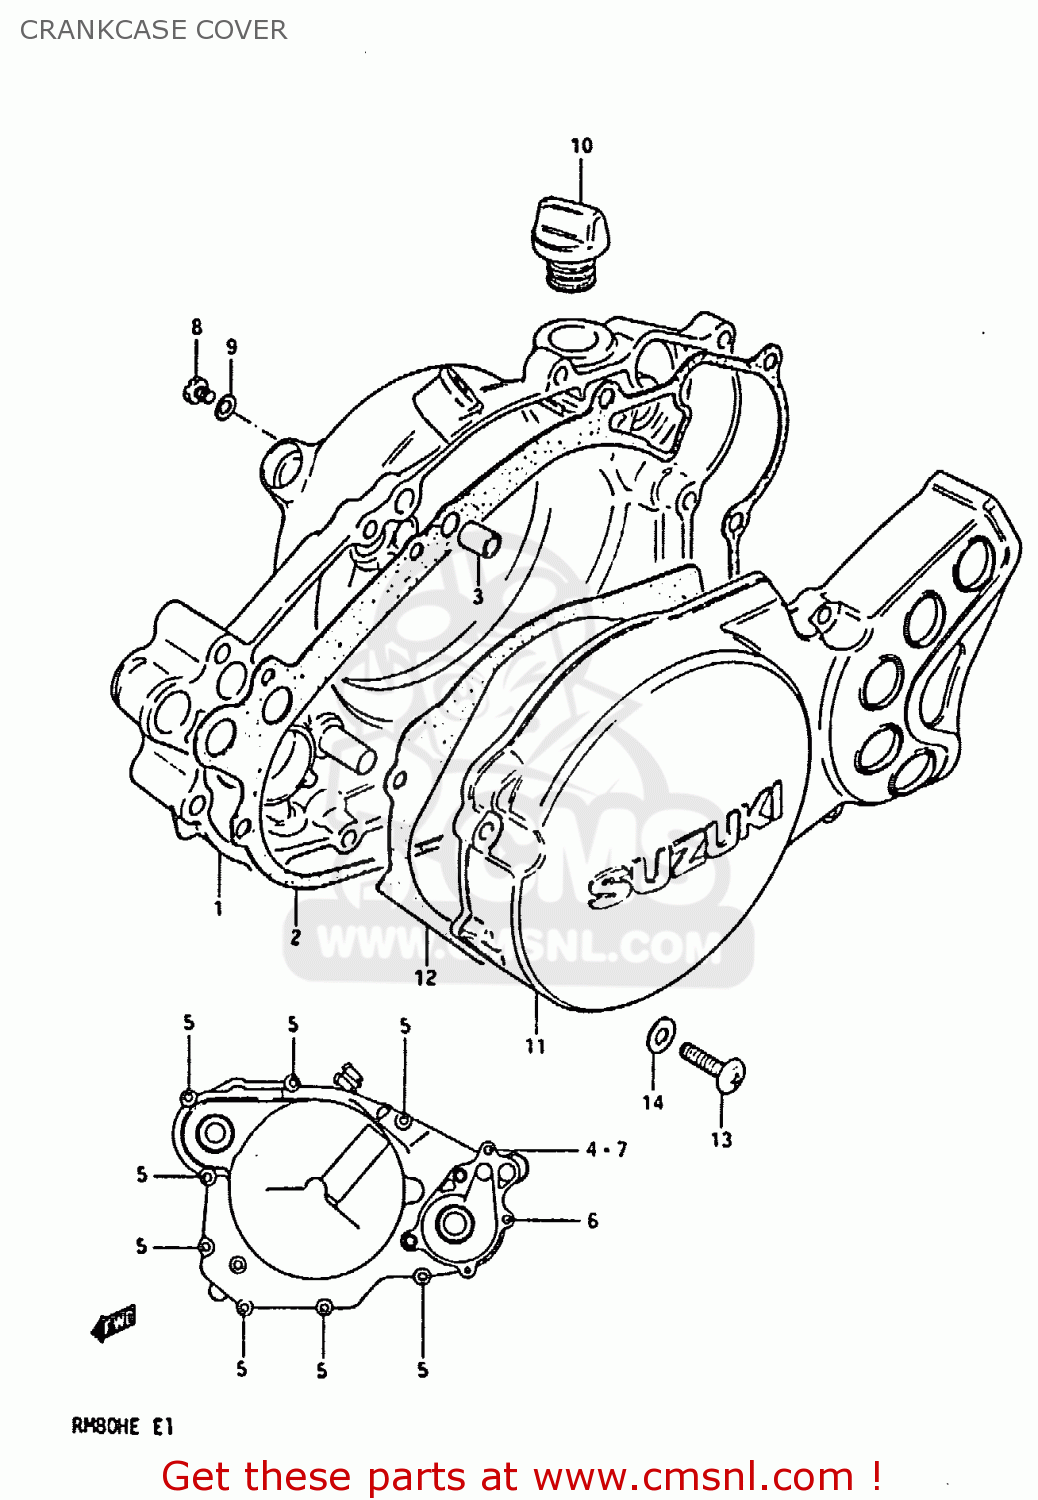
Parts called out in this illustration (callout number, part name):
1	COVER,CLUTCH
2	GASKET,CLUTCH COVER (MCA)
3	PIN
4	WASHER
5	SCREW
6	SCREW
7	SCREW
8	SCREW(6X10)
9	GASKET(6.2X11X1) (NAS)
10	PLUG
11	COVER,MAGNETO
12	GASKET,MAGNETO COVER (NAS)
13	SCREW 5X20
14	WASHER,5MM
